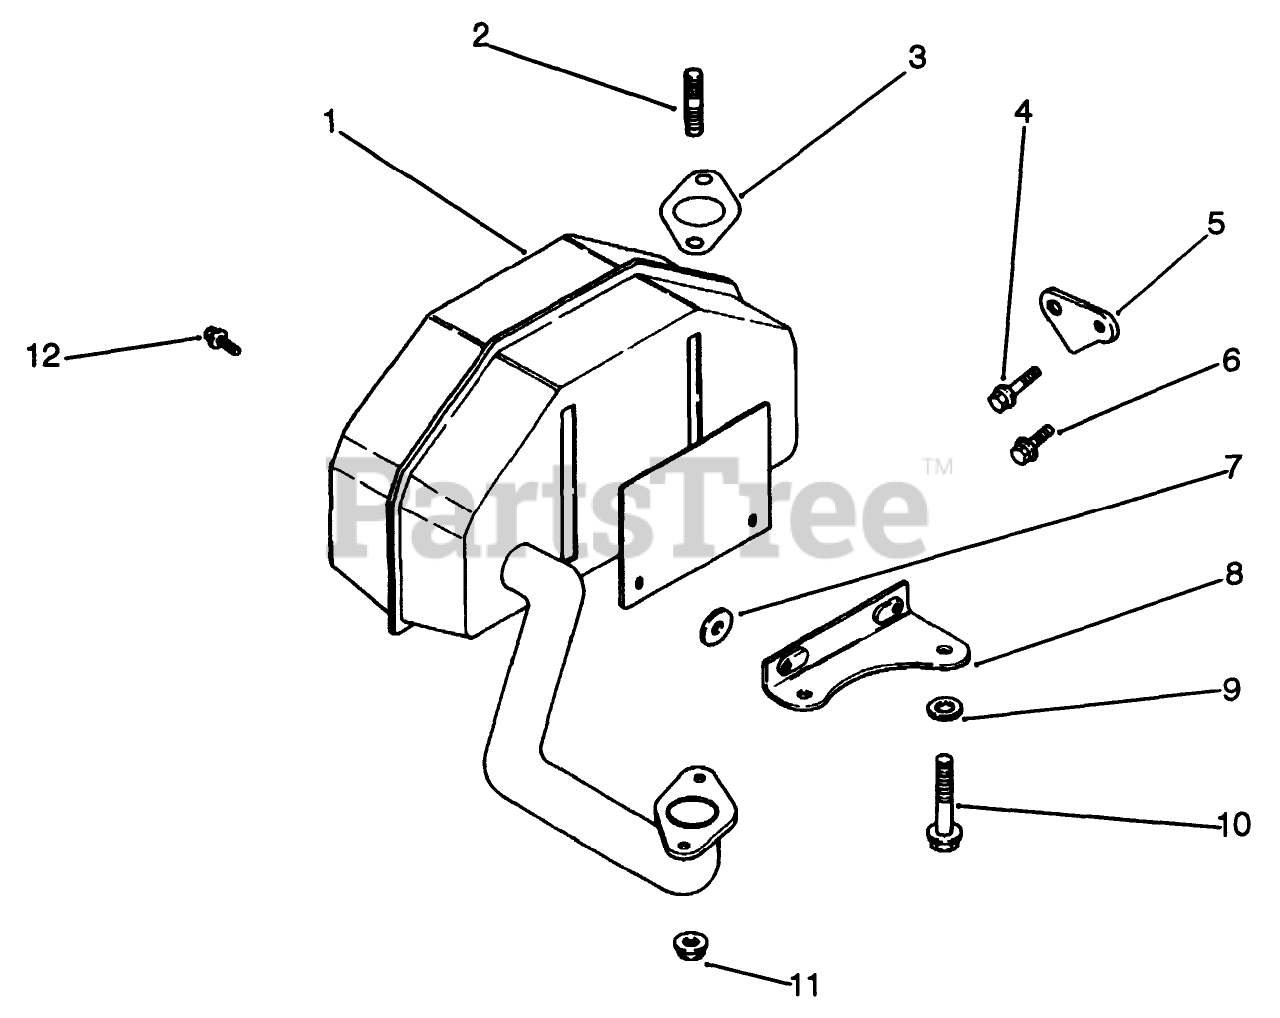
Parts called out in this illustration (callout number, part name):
1	Muffler
3	Gasket-Exhaust Manifold (Only On: 72043, 72042, 72363, 72062)
5	Strap-Lifting (Only On: 72042,72043,72062,72063)
7	Washer
8	Bracket-Muffler
9	Washer (Only On: 72042, 72063, 72062, 72043)
11	Nut-Muffler
